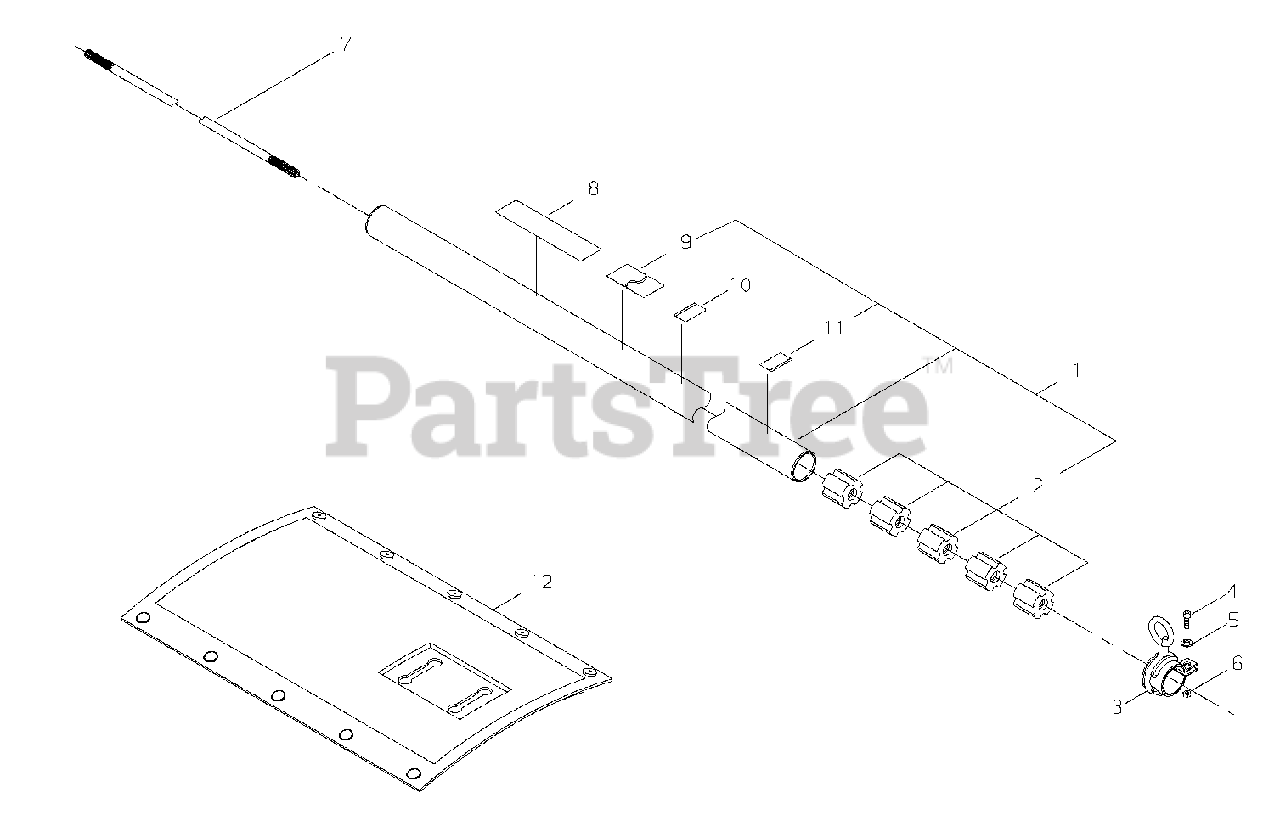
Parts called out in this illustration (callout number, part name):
1	MAIN PIPE ASSY
2	BUSHING
3	HANGER
4	SCREW - 5X12
5	LOCKWASHER - 5
6	NUT - 5
7	PIPE, MAIN
8	LABEL - TRADE
9	LABEL - CAUTION
10	LABEL - INSTRUCTION
11	LABEL - HANDLE LOCATION
12	PROTECTOR
